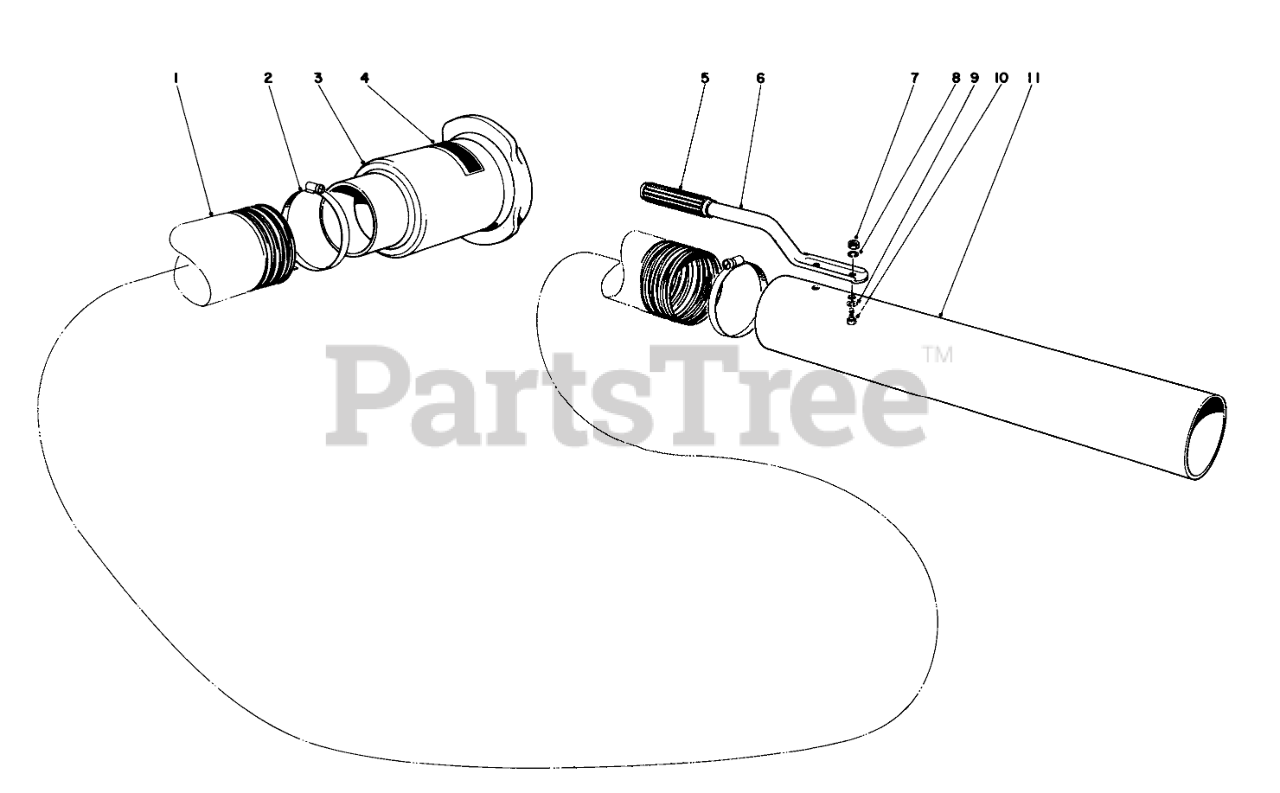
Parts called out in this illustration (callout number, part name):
2	Clamp
3	Hose Adaptor
4	Decal
6	Handle
7	NUT-HEX
8	WASHER-LOCK
9	WASHER-FLAT
10	Screw
11	Nozzle
